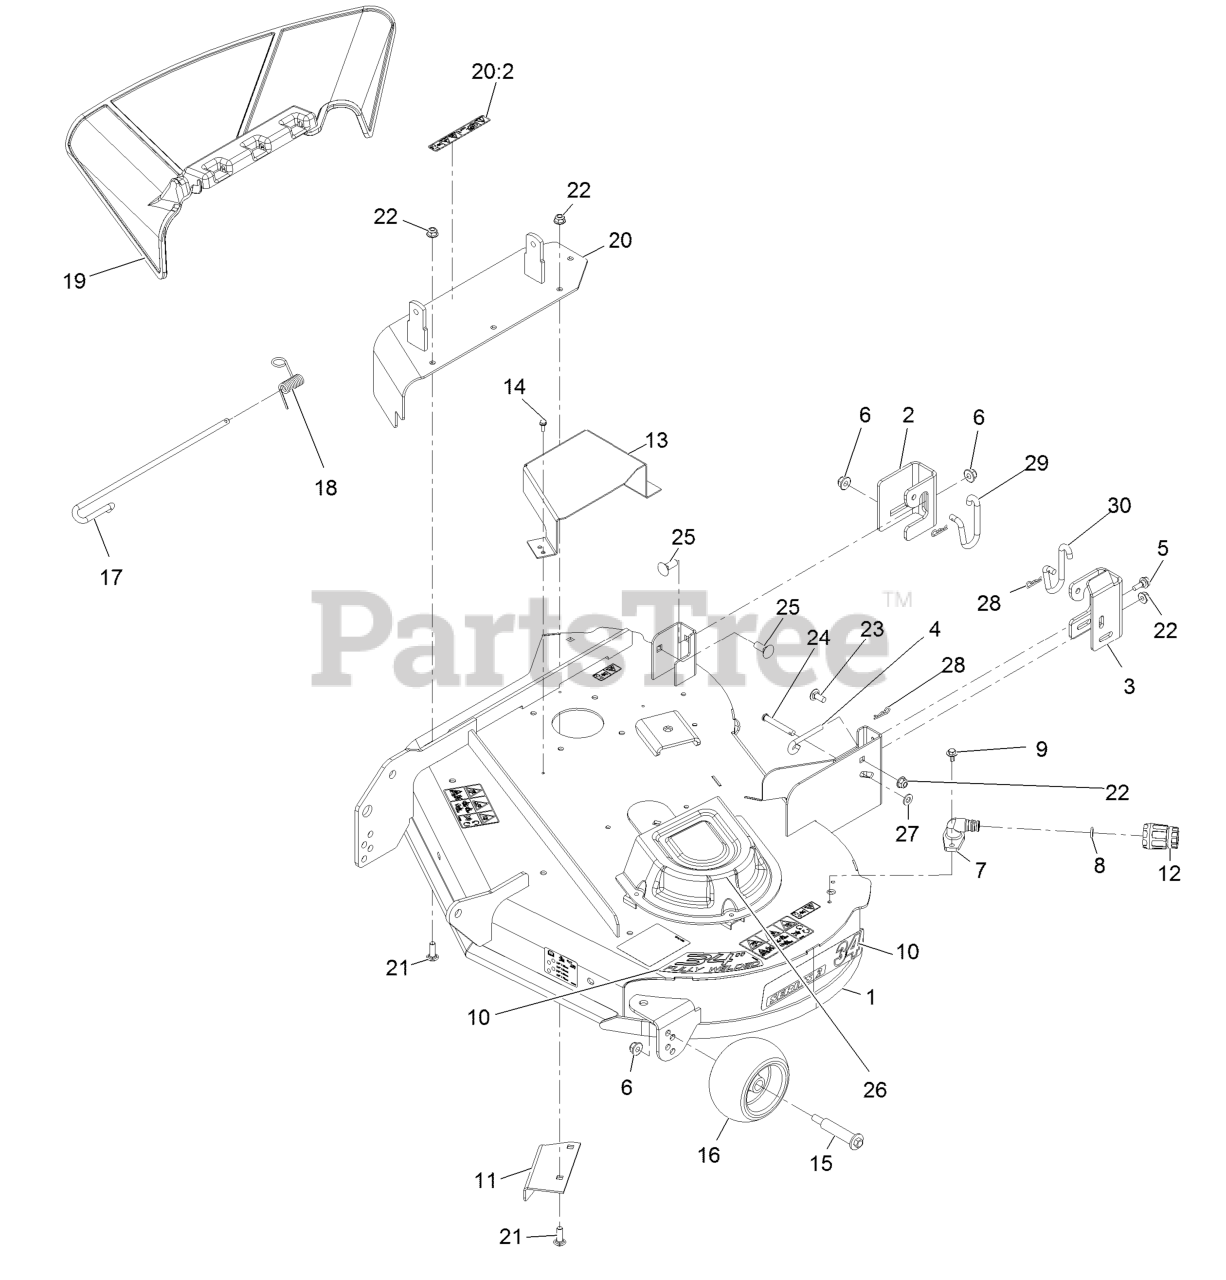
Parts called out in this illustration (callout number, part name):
1	34 INCH DECK AND DECAL AS
2	BRACKET-HANGER, RH
3	BRACKET-HANGER, LH
4	ROD-LEVEL, DECK
5	SCREW-SHOULDER,HWH
6	NUT-HF, NI
9	SCREW-HHFTF
10	Decal - Series 2 34
11	BAFFLE-CUTOFF
12	CONNECTOR-HOSE
13	COVER-DECK BELT
14	SCREW-TAPTITE
15	BOLT-SHOULDER
16	ROLLER-SCALP, ANTI
17	PIN-CHUTE
18	SPRING-TORSION
19	DEFLECTOR-DISCHARGE
20	COVER ASM W/DECAL
20:2	DECAL-DANGER
21	SCREW-CARR
22	NUT-HF, NI
23	SCREW-CARR
24	PIN-CLEVIS
25	BOLT-CARR
26	COVER-BELT
27	WASHER-PLAIN
28	PIN-COTTER
29	LINK-RETENTION, DECK (RH)
30	LINK-RETENTION, DECK (LH)
